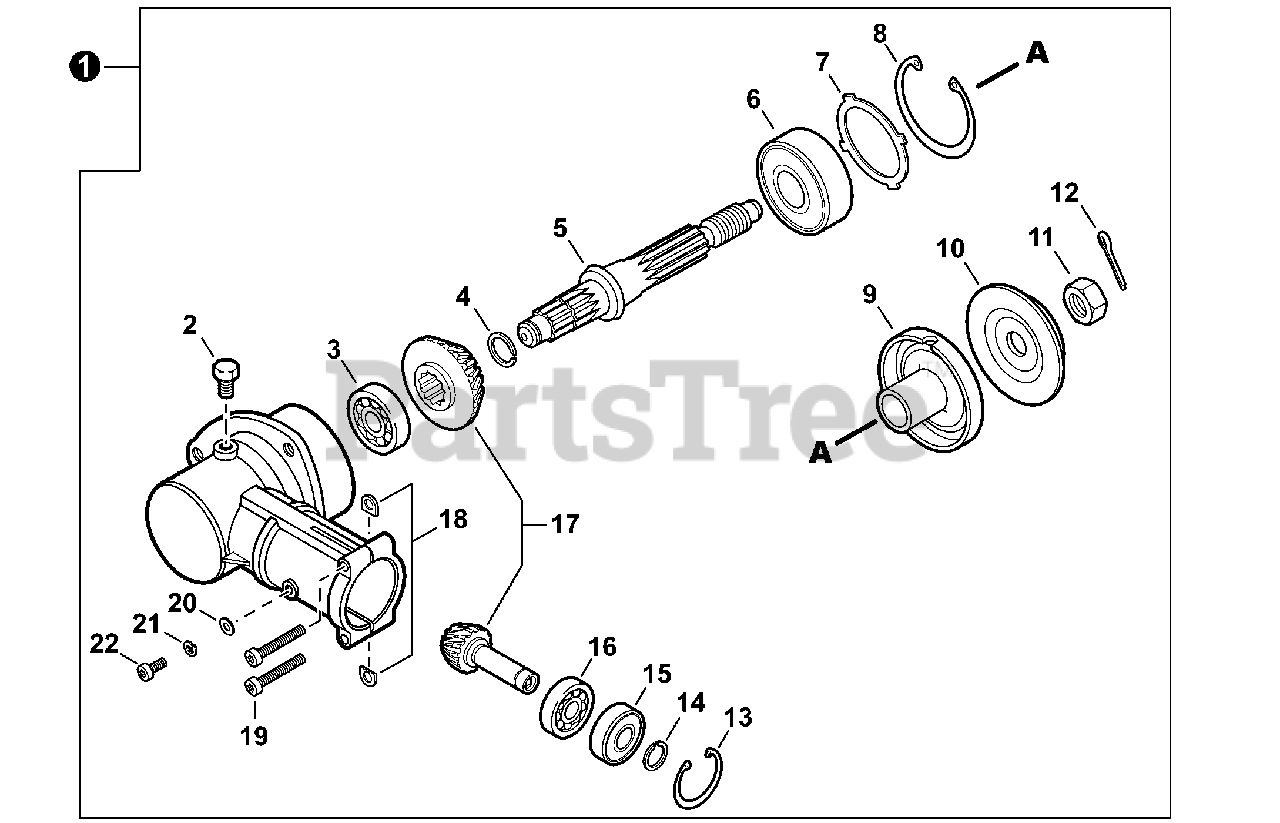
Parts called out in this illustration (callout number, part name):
1	GEAR CASE ASSY
2	BOLT M8×8
3	BEARING, BALL 609
4	RING, SNAP Ø12
5	SHAFT, GEAR
6	BEARING, BALL 6201
8	RING, SNAP Ø32
9	PLATE, ADAPTOR - UPPER
10	PLATE, ADAPTOR - LOWER
11	NUT 10×1.25 LH
12	PIN, COTTER 2×22
13	RING, SNAP Ø22
14	RING, SNAP Ø10
15	BEARING, BALL 6900-Z
16	BEARING, BALL 6900
17	GEAR SET
18	D-WASHER
19	BOLT, TORX 5×25
20	WASHER, FLAT 5.5×10×0.8
21	WASHER, SPRING 5
22	BOLT, TORX 5×12
